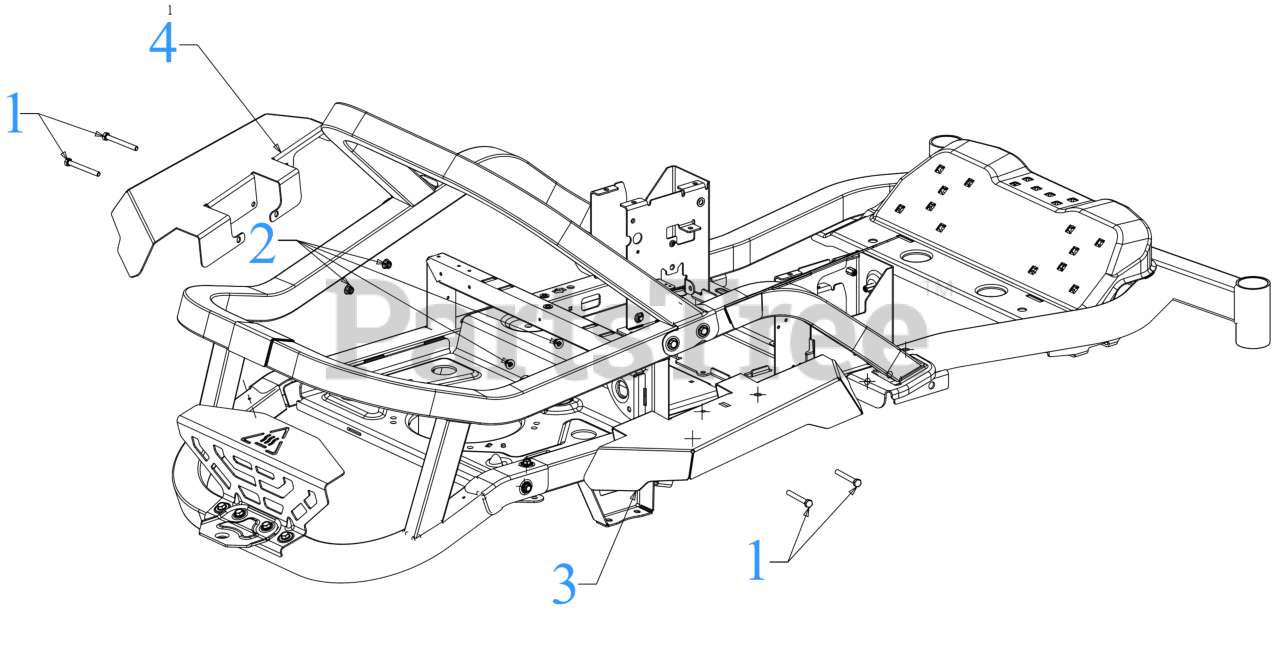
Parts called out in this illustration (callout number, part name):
1	HEX SCREW 5/16-18 x 2.75
2	FLANGE LOCK NUT 5/16-18
3	REAR FENDER (RH)
4	REAR FENDER (LH)
